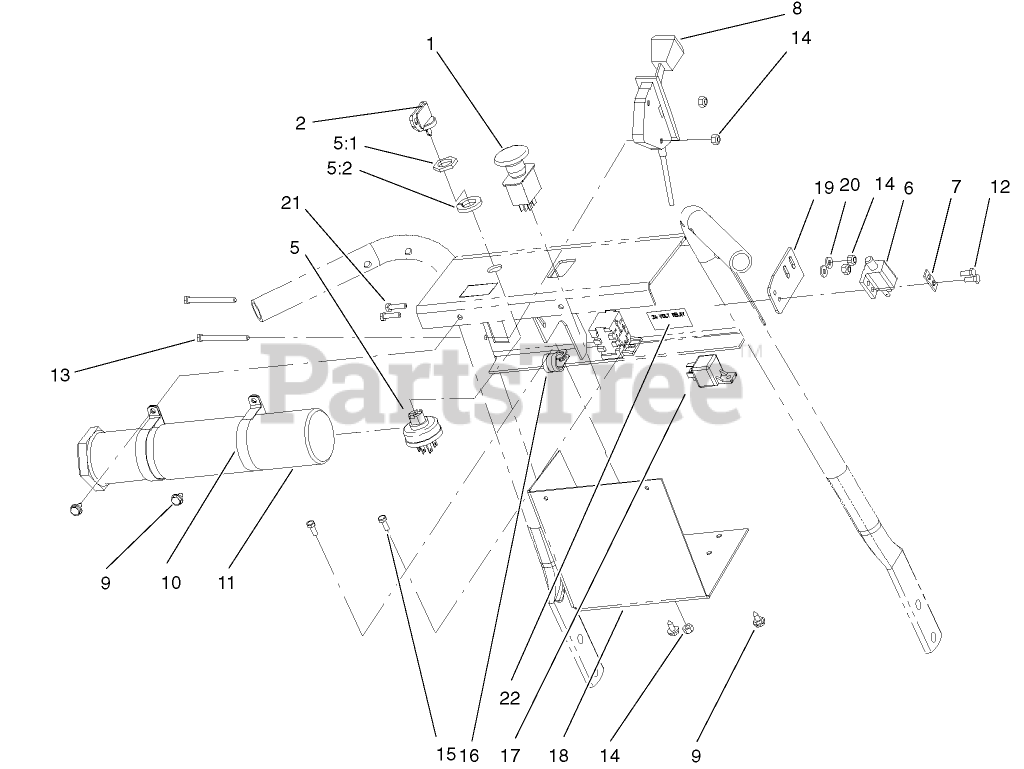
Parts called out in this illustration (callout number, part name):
1	SWITCH-PTO
2	KEY-IGNITION
5	SWITCH-ON / OFF
5:1	NUT-HH
5:2	WASHER-TOOTH, INTERNAL
6	SWITCH-POLE, SINGLE
7	PLATE-SWITCH
8	CONTROL-THROTTLE
9	SCREW-HWHTF
10	CLAMP-R
11	TUBE-MANUAL
12	SCREW-TAPTITE
13	SCREW-SHH
14	NUT-LOCK, NI
15	SCREW-HWH
16	CLAMP-R
18	BRACKET-COVER
19	PLATE-MOUNTING, SWITCH
20	WASHER-FLAT
21	SCREW-HWH
22	DECAL-RELAY, 24 VOLT
